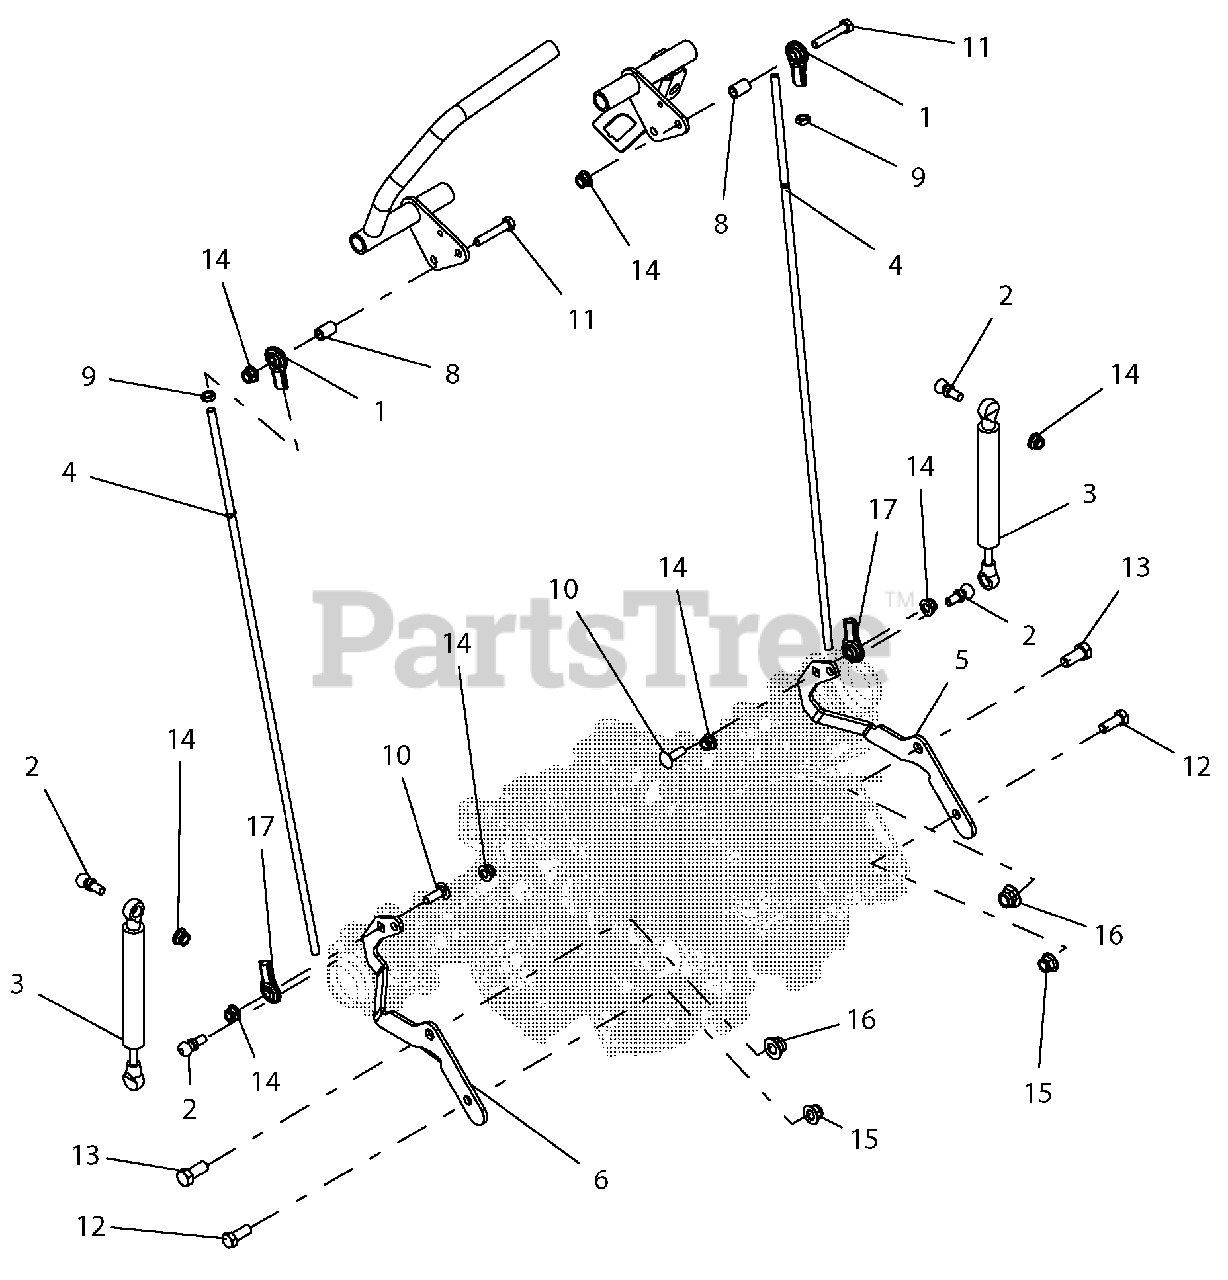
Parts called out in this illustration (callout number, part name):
1	ALIGNABALL, 5/16 LH THREAD
2	STUD-BALL
3	CONTROL DAMPER
4	ROD, STEERING
5	BRKT, LH TRANS CONTROL
6	BRKT, RH TRANS CONTROL
8	BSHG-SLV .328X.50X.75
9	NUT, JAM -LH .31-24 YWZC
10	BLT-RDHDSQSHNK .31-18X1.00 G5 Y
11	BLT-HEX .31-18X1.75 GR5 YWZC
12	BLT-HEX .38-16X1.00 GR5 YWZC
13	BLT-HEX .44-14X1.00 GR5 YWZC
14	NUT-LK-NYL-FLG .31-18 YWZC
15	NUT-LK-NYL-FLG .38-16 YWZC
16	NUT-LK-NYL-FLG .44-14 YWZC
17	ALIGNABALL, 5/16 RH THREAD
